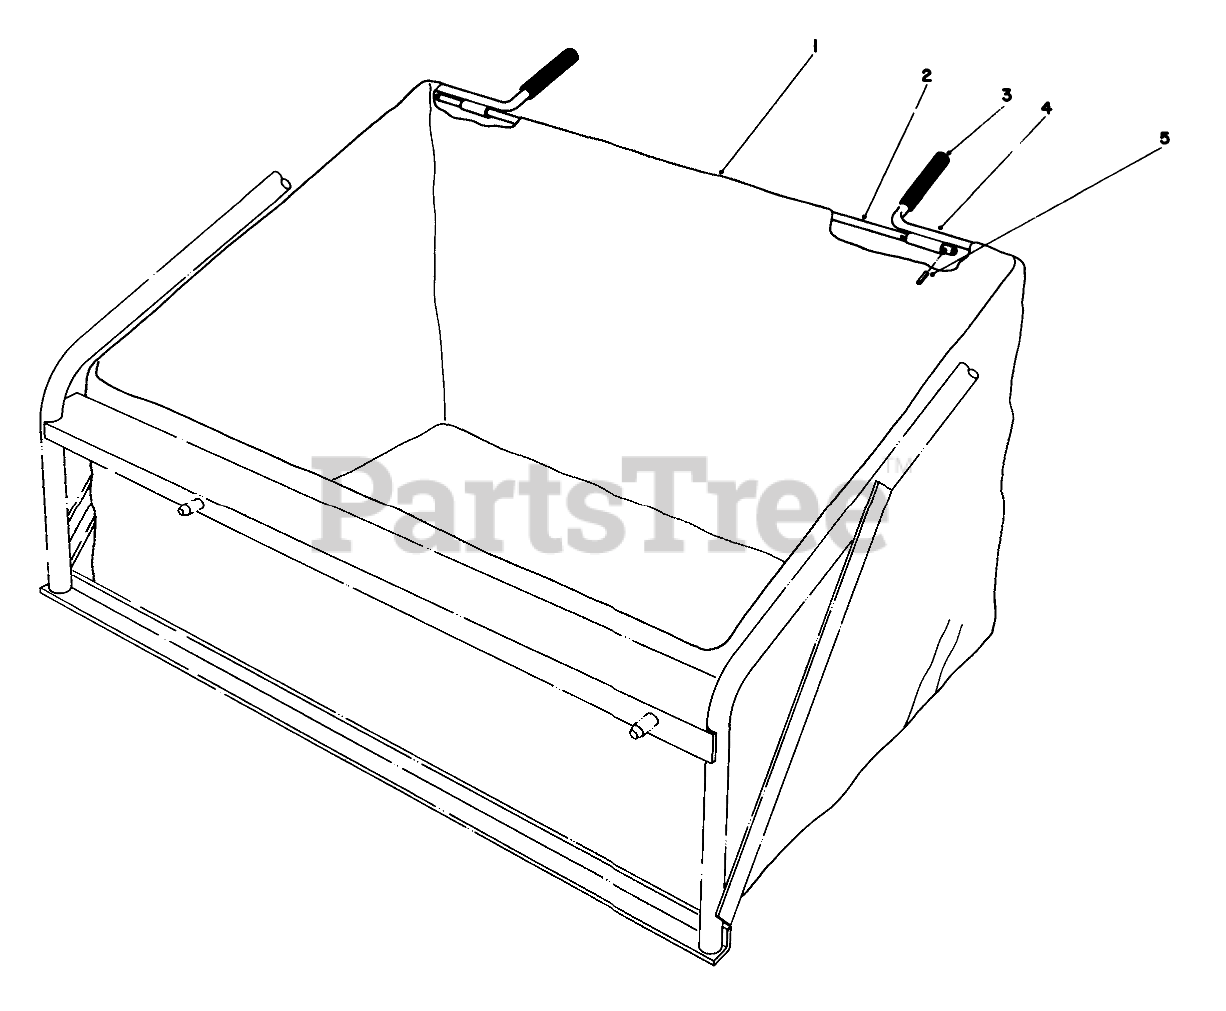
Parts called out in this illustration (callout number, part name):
1	Bag-Leaf Catcher
2	BAG FRAME ROD
3	BAG HANDLE GRIP
4	BAG FRAME WA B
5	PIN-ROLL
